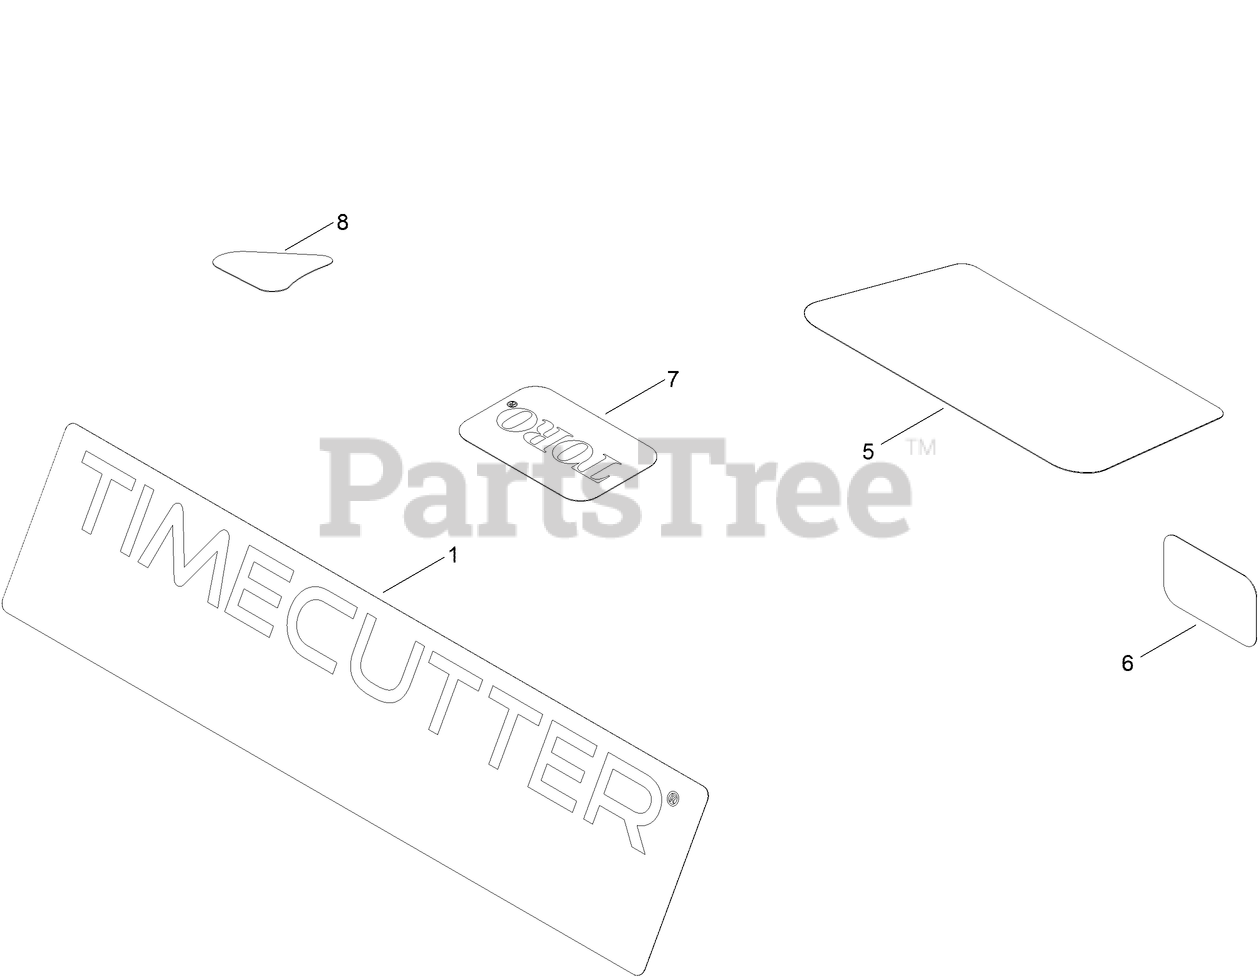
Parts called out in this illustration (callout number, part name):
1	DECAL-TIMECUTTER
5	DECAL-ENGINE
6	PLACARD-INTAKE
8	DECAL-DRAIN, OIL
